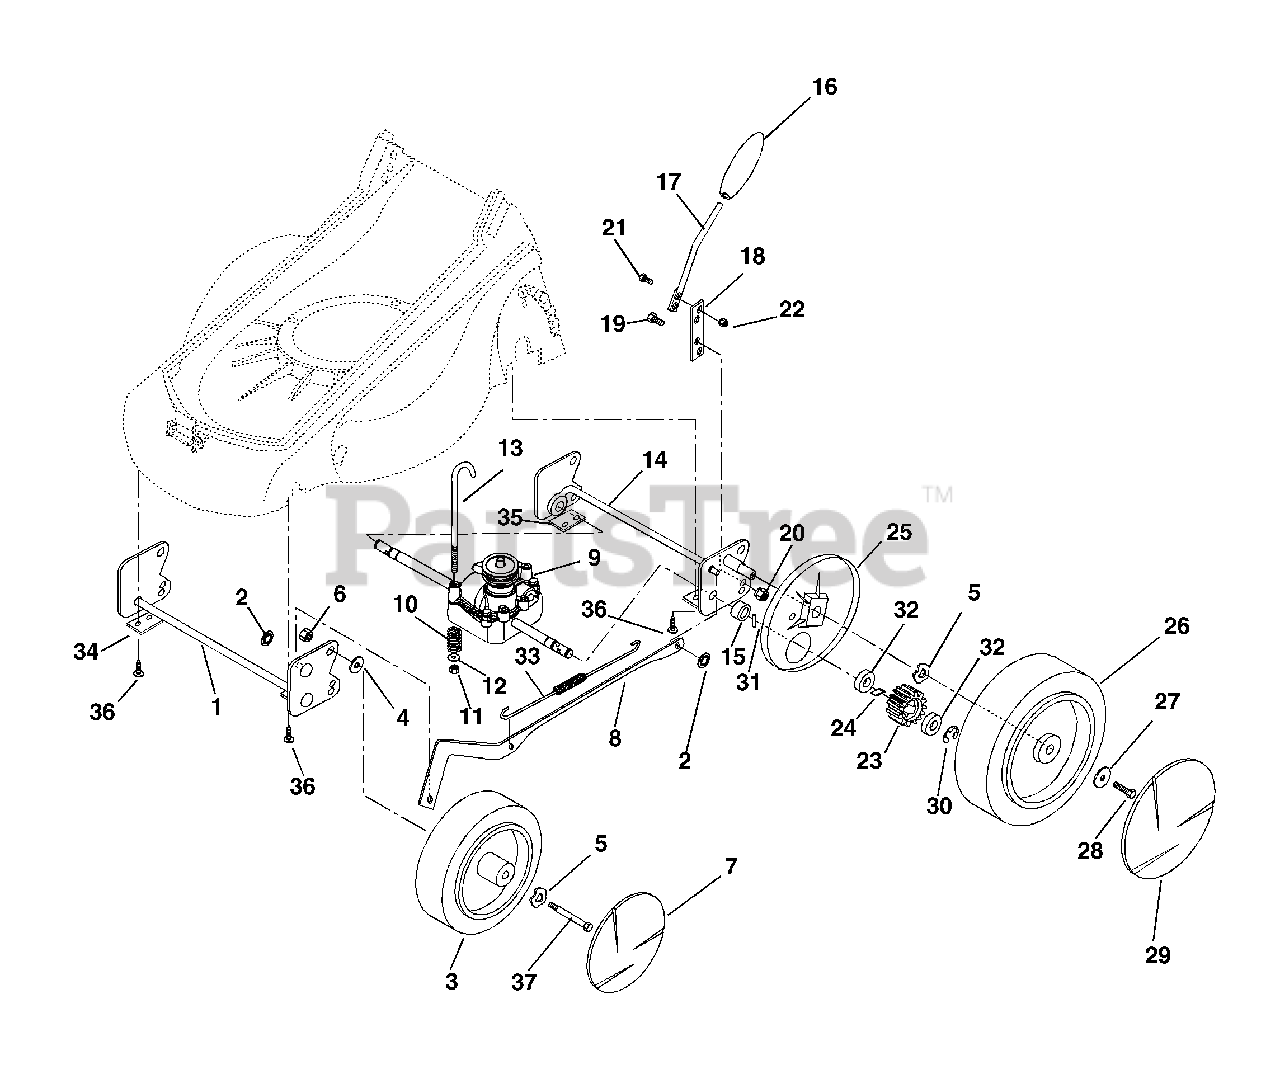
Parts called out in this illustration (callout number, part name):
1	AXLE, FRONT ASSEMBLY
2	CLIP, STAR LOCK TRAILING SHLD
3	WHEEL, FRONT W/BEARINGS
4	WSHR, 8.3X22X2
5	WSHR, WEAVY 13X24X0.6
6	NUT, LK M8
7	COVER, FRONT WHEEL
8	ROD, CONNECTING
9	TRANSMISSION
10	SPRING, TRANSMISSION RETURN
11	NUT, LK M5
12	WSHR, 5.3X10X1
13	ROD, V BELT TENSIONER
14	AXLE, REAR ASSEMBLY WELDMENT
15	BEARING, BALL 27M-12.15
16	KNOB, HEIGHT ADJUSTMENT LEVER
17	ROD, HEIGHT ADJUSTMENT LEVER
18	PLATE, HEIGHT ADJMT SPRG STL
19	BOLT, M6-12
20	NUT, LK M6
21	BOLT, M4X12
22	NUT, M4
23	PINION, WHEEL DRIVE
24	KEY, DRIVE RATCHET
25	COVER, WHEEL DRIVE
26	WHEEL, REAR W/BEARINGS
27	WSHR, 6.5X27X1.5
28	BOLT, M6X16 SELF TAPPING
29	COVER, REAR WHEEL
30	RING, SNAP TRANSMISSION SHAFT
31	PIN, ROLL REAR AXLE LOCK
32	BUSHING, PINION
33	SPRING, HEIGHT ADJUSTMENT
34	PLATE, FRONT AXLE MOUNTING
35	PLATE, REAR AXLE MOUNTING
36	SCREW, KA 40X16
37	BOLT, SHOULDER FRT WHL AXLE
